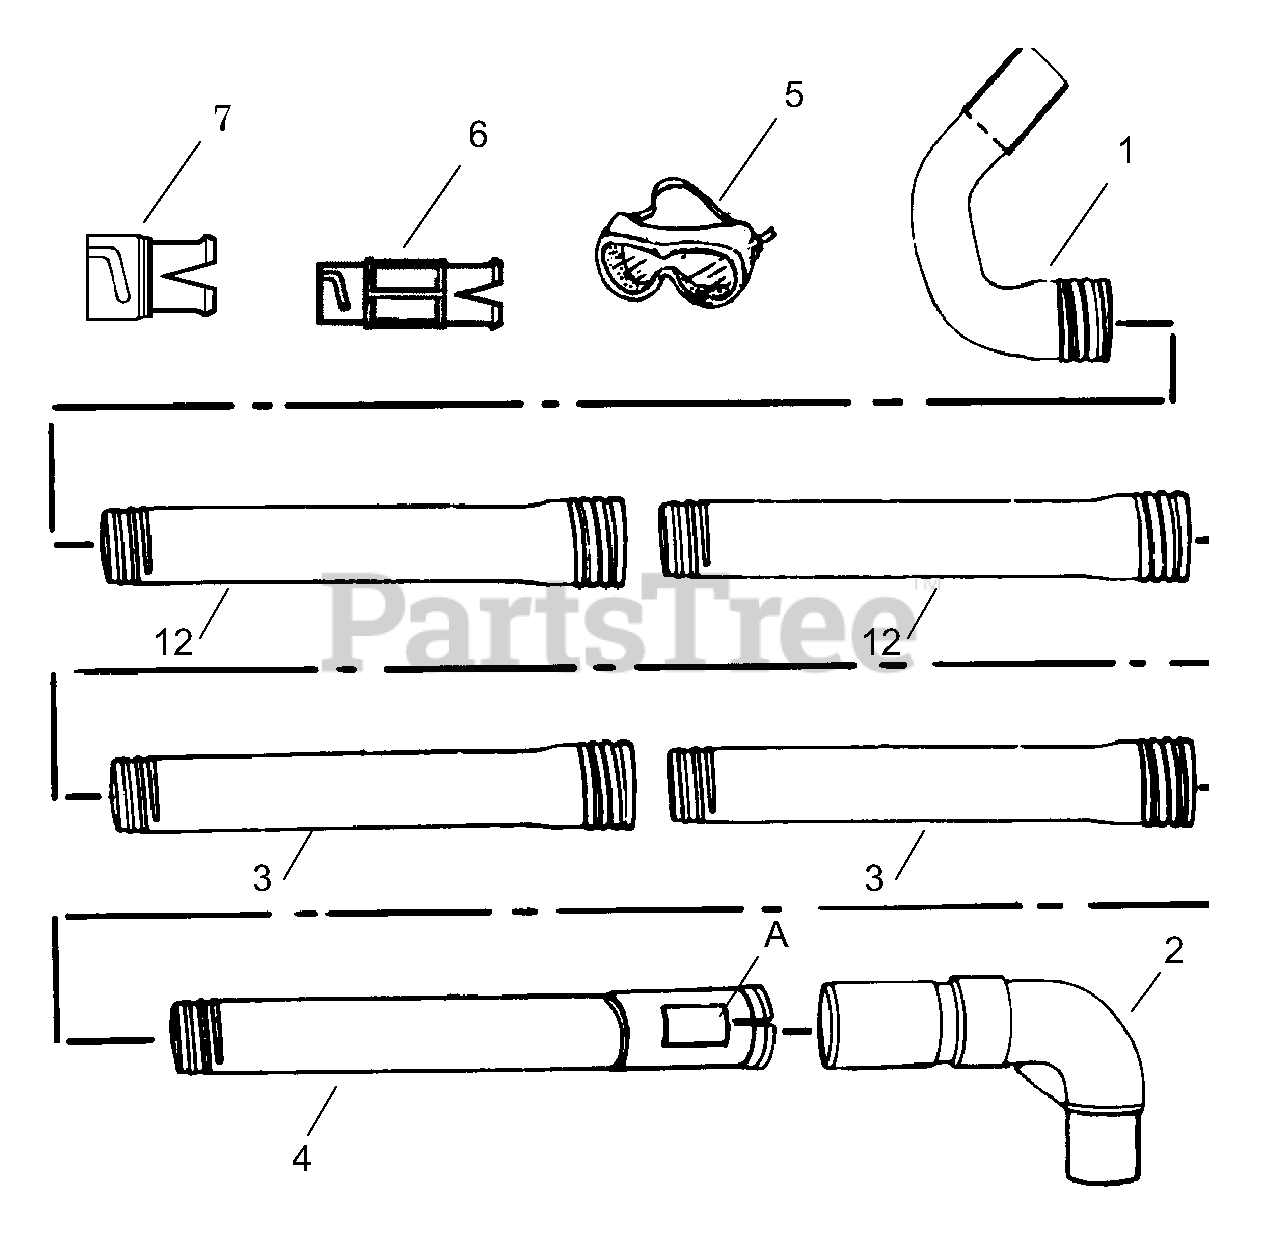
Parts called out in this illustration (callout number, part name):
2	Elbow & Spacer Ring
3	Extension Tube
4	Pivot Tube
5	Goggles
6	Adapter-Gas
7	Adaptor-Electrics
A	Warning Decal (Not a serviceable part)
